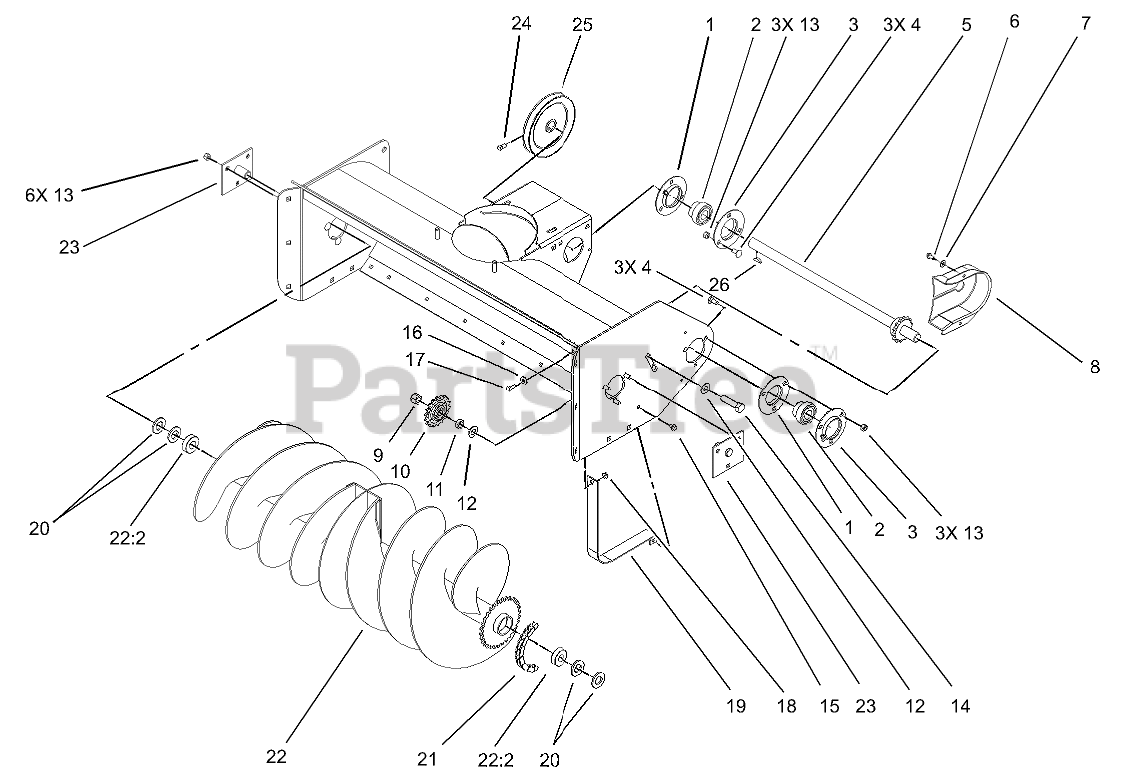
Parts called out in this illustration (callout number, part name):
1	Flange
2	BEARING AND COLLAR
3	FLANGE-ZERK RELUBE
4	BOLT-CARR
5	SHAFT W/SPRKT
6	SCREW-HWH
7	WASHER-FLAT
8	GUARD-CHAIN
9	NUT-LOCK, NI
10	SPROCKET-IDLER
11	SPACER
12	WASHER-FLAT
13	NUT-LOCK, NI
14	SCREW-HH
15	SCREW-HHF
16	WASHER-FLAT
17	SCREW-HH
18	NUT-KEPS
19	GUARD-INNER
20	WASHER-FLAT
21	CHAIN-64 PITCHES
22	AUGER ASM
22:2	BEARING-BALL
23	SUPPORT
24	SCREW-SQH
25	PULLEY
26	KEY-HI-PRO
